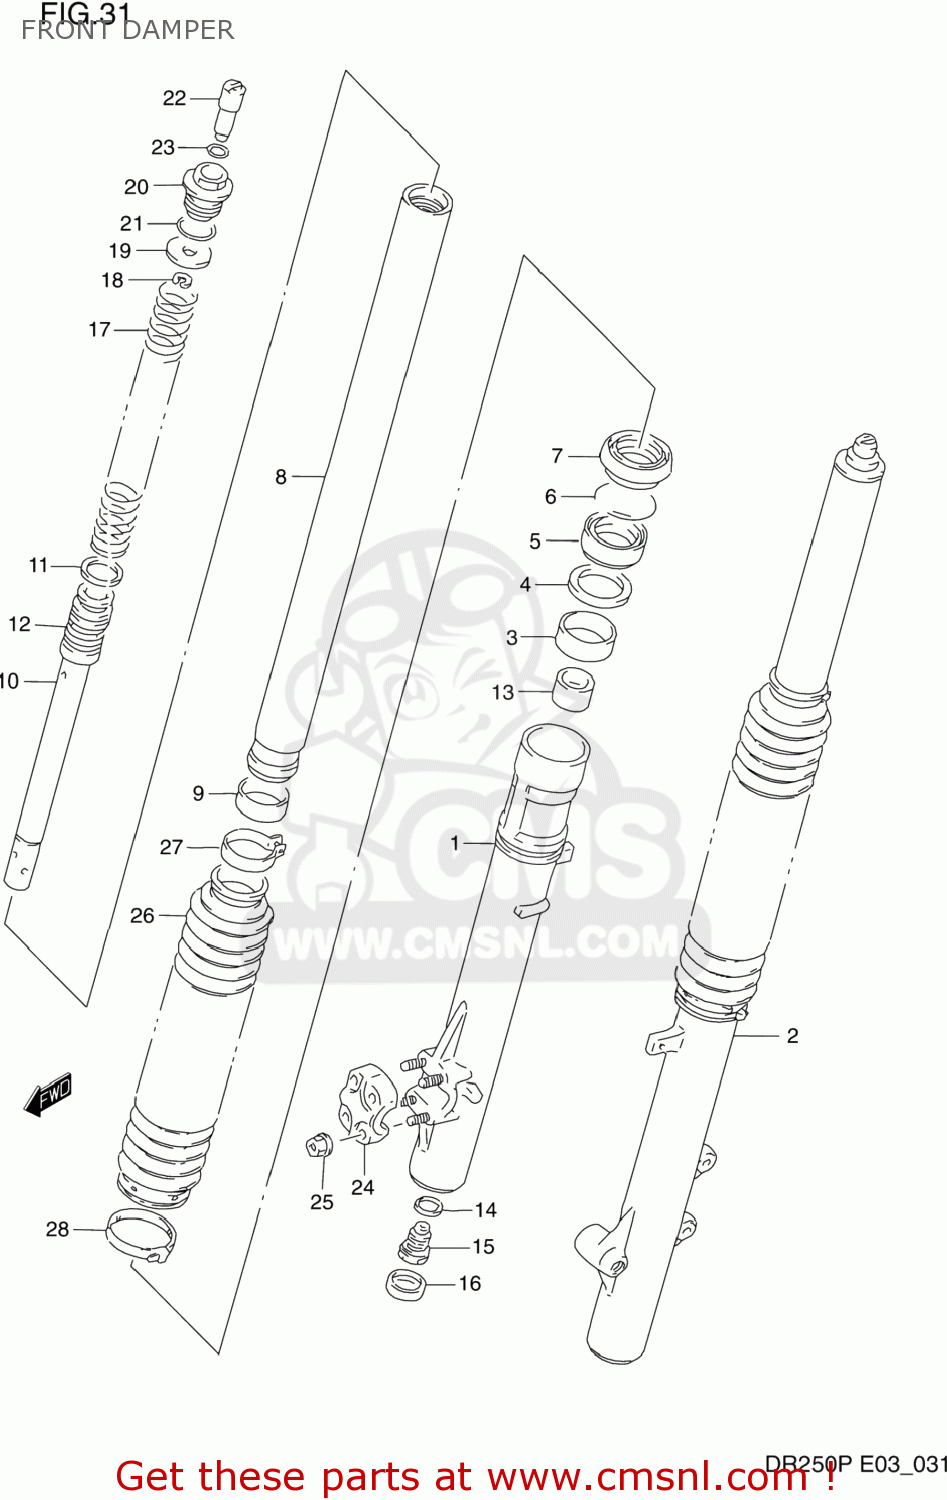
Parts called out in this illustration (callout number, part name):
1	TUBE,OUTER,R
2	TUBE,OUTER,L
3	BUSH,GUIDE
4	SPACER,SEAL
5	SEAL,OIL
6	CIRCLIP,FORK OIL SEAL
7	DUST SEAL
8	TUBE,INNER
9	BUSH,SLIDE
10	CYLINDER
11	RING,PISTON
12	SPRING,REBOUND
13	PIECE,OIL LOCK
14	GASKET (NAS)
15	BOLT,LWR
16	CAP,LOWER
17	SPRING,MAIN
18	E RING
19	SEAT,SPRING
20	BOLT,FORK
21	O RING
22	ADJUSTER,SPRING
23	O RING
24	HOLDER,AXLE
25	NUT,HOLDER
26	BOOT
27	BAND,BOOT UPR
28	BAND,BOOT LWR
